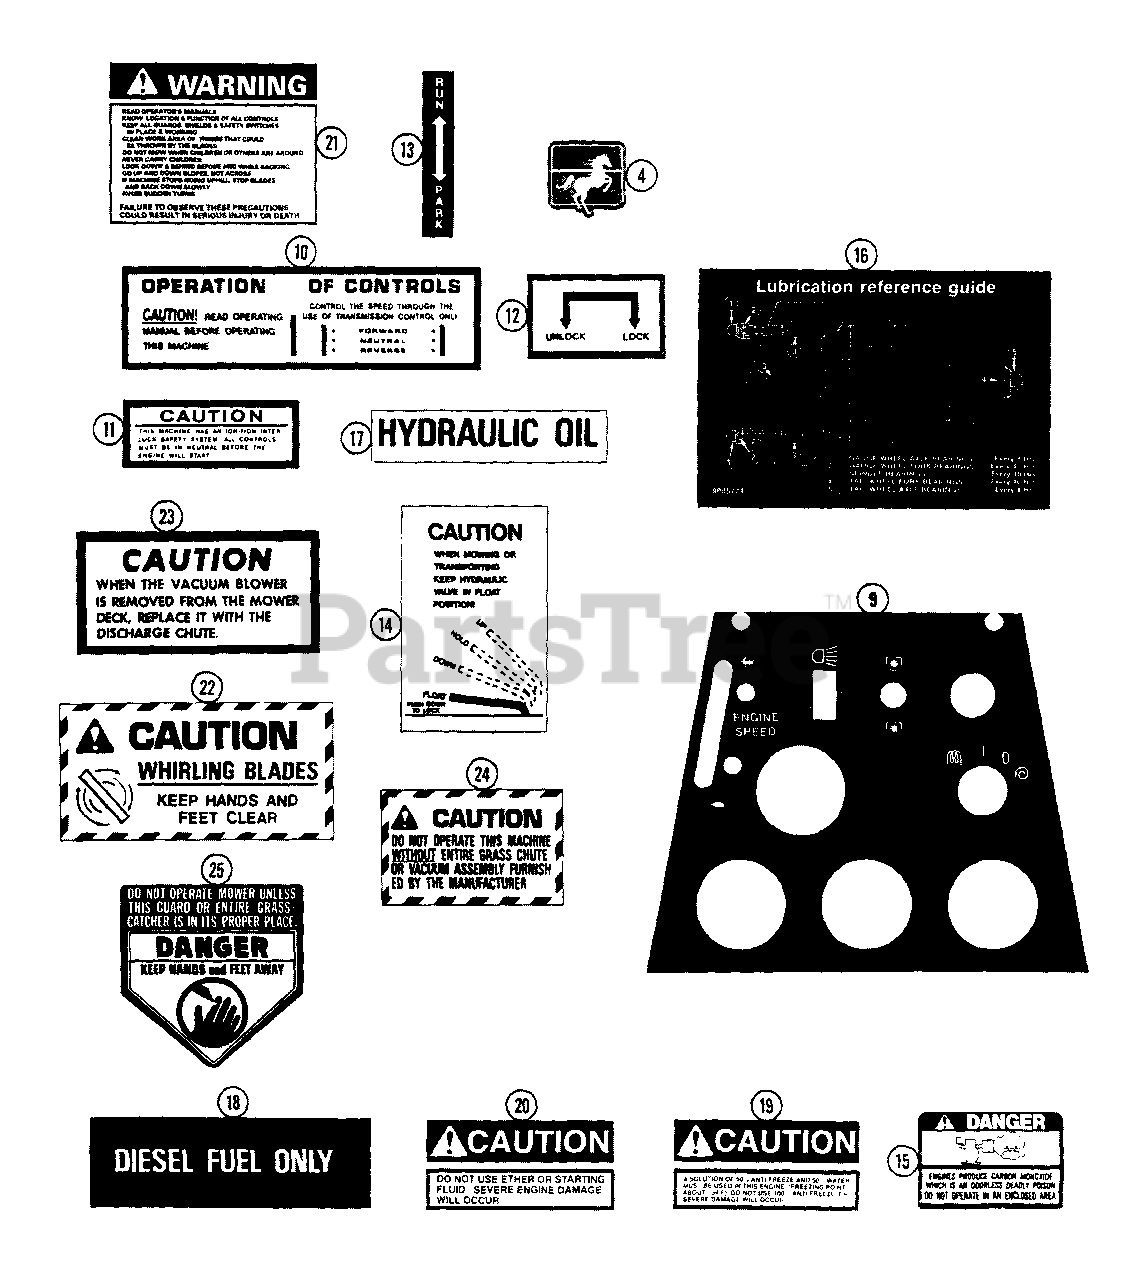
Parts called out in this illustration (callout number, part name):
4	MEDALLION - White "Horse"
9	DECAL - instrument panel
10	DECAL - operation
11	DECAL - "CAUTION" interlock
12	DECAL - unlock/lock
13	DECAL - run/park
14	DECAL - "CAUTION" hydraulic lift
15	DECAL - "DANGER" carbon monoxide
16	DECAL - lubrication
17	DECAL - hydraulic oil
18	DECAL - diesel fuel only
19	DECAL - anti-freeze
20	DECAL - ether
21	DECAL - "WARNING"
22	DECAL - "WHIRLING BLADES"
23	DECAL - "CAUTION" discharge
24	DECAL - "CAUTION" grass chute
25	DECAL - "DANGER"
